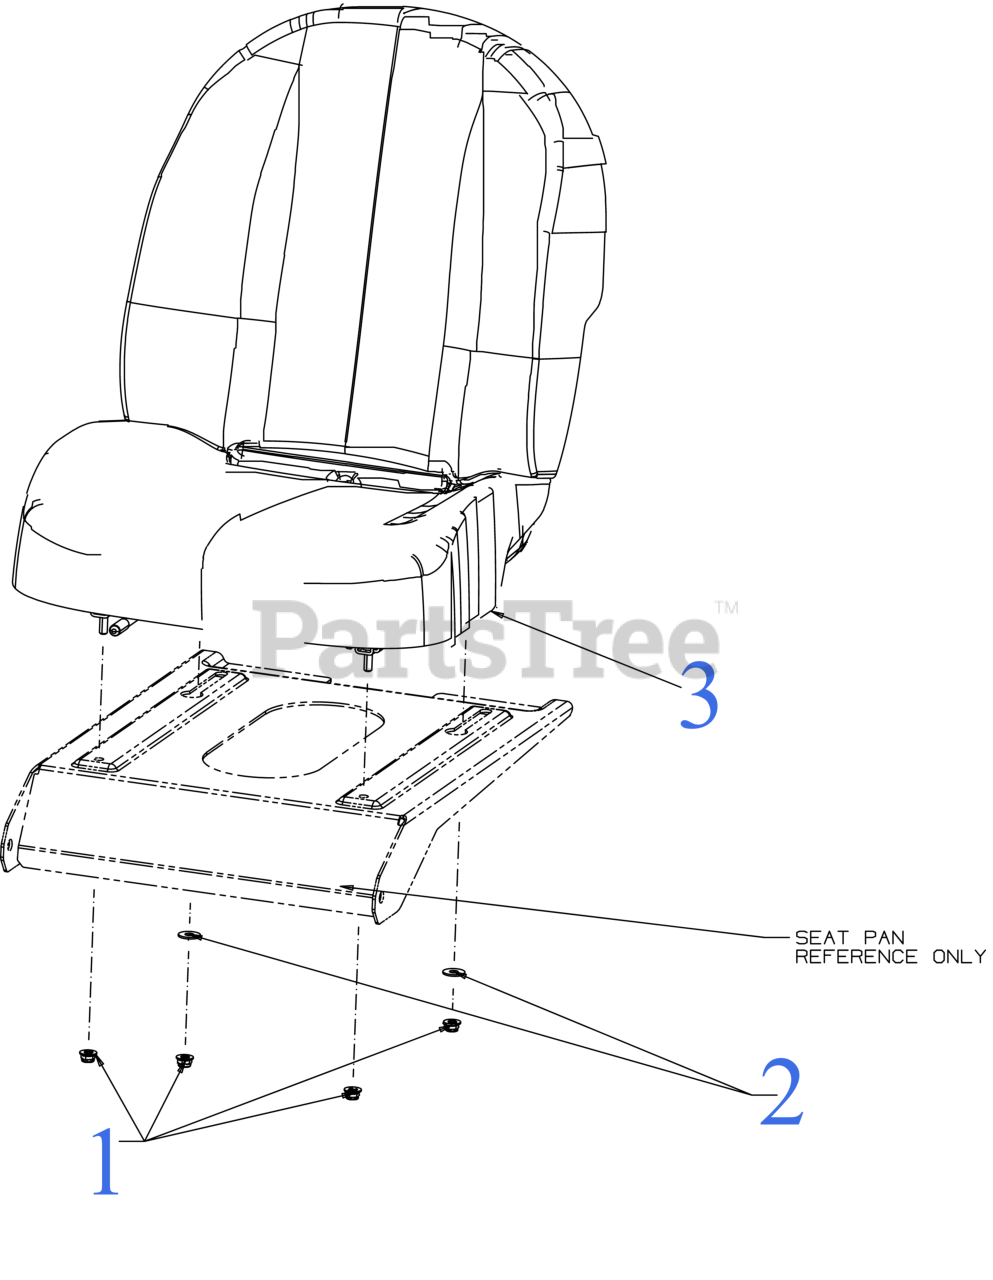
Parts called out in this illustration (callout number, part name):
1	FLANGE LOCK NUT 5/16-18
2	FLAT WASHER
3	SEAT (HI BACK/CUB/SLIDE)
3	SEAT SWITCH N/C,N/C
